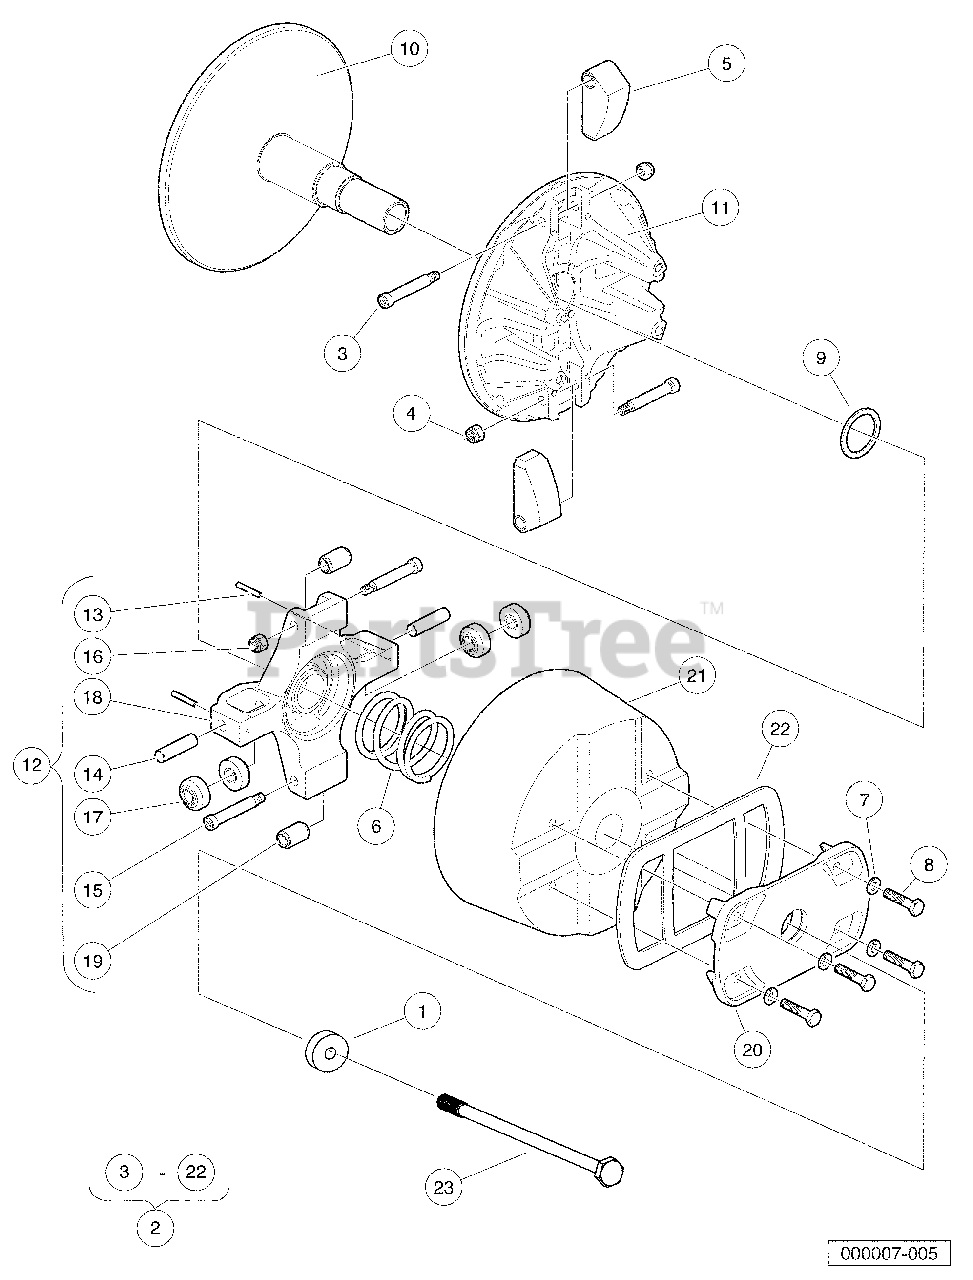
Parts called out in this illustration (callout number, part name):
1	Washer, Stepped
2	Clutch, 4x4, Gas, W/cover
3	Screw, Shlder Hex, .312 X 1.75
4	Nut, Lock Hex, 1/14-20, Flexlc
5	Sub Assy, Wt Clutch, Gas
6	Spring, Compression, Primary
7	Washer, Lock, H-Spring, 1/4
8	Screw, Cap, Hex Hd, 1/4 X 1.25
9	Shim, 1.63 X 1.33
10	Subassembly, Drive Clutch
11	Subassembly, Moveable, Drive Clutch
12	Spider Subassembly
13	Pin, Spring Slotted,1.25 X 1.0
14	Pin, Dowel, .375 X 1.50
15	Screw, Shlder Hex, .312 X 1.75
16	Nut, Lock Hex, 1/14-20, Flexlc
17	Roller, Torque, Gas
18	Spider, Drive Clutch.
19	Sub Assy, Roller Weight
20	Cover, Drive Clutch
21	Cover, Clutch, 4x4.
22	Gasket, Cover, Clutch, 4x4
23	Bolt, M8 X 1.25 X 200, Loctite
